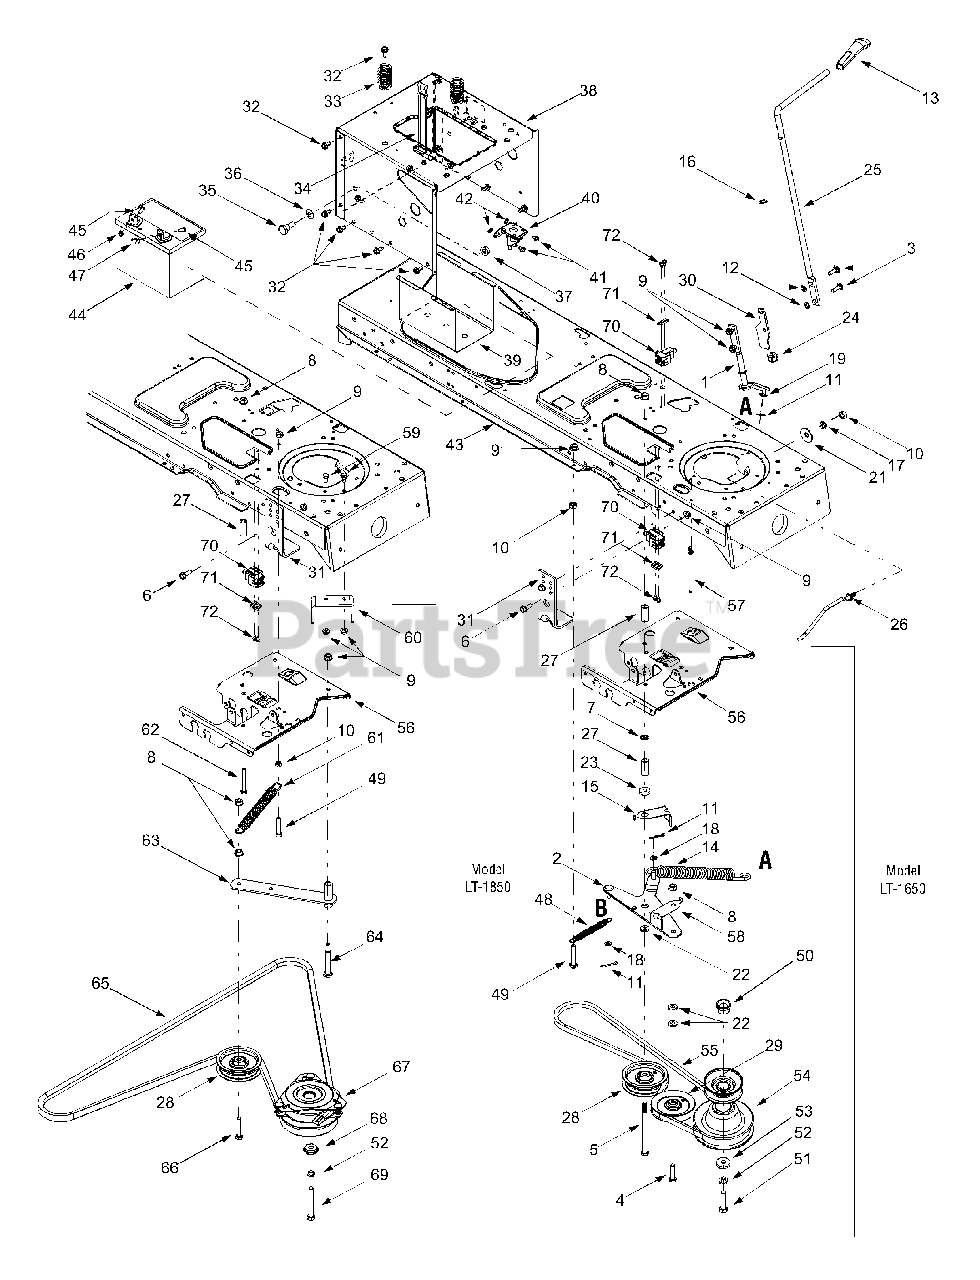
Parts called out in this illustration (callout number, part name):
1	PTO Engage Lever Assembly
4	Hex Cap Screw, 3/8-16 x 1.5
5	Hex Cap Screw, 3/8-16 x 5.5
6	Hex Head Washer Screw, 5/16-18 x .875
7	Push Nut, 3/8
8	Flange Lock Nut, 3/8-16
9	Flange Lock Nut, 5/16-18
10	Hex Nut, 5/16-18
11	Cotter Pin, 1/8 x 1.25
12	Speed Nut, .3125
13	PTO Knob
14	Extension Spring, .75 x 6.75
16	Flat Washer, .510 x .750 x .033
17	Lock Washer, 5/16
18	Flat Washer, .385 x .62 x .063
19	Flat Washer, 5/16
21	Bell Washer, .39 x 1.13 x .062
22	Flat Washer, .407 x .812 x .135
23	Shoulder Spacer, .380
24	Hex Split Flange Bearing, .5
26	Belt Keeper Rod
27	Spacer, 3/8 x 1.54
28	Idler Pulley, 3.5
29	Idler Pulley, 4.0
32	Self Tapping Screw, 5/16-18 x .625
33	Compression Spring, 1.28 x 3.125
34	Battery Strap
35	Shoulder Screw, .625 x .5, 7/16-20
36	Bell Washer, .45 x 1.0 x .062
37	Flange Lock Nut, 7/16-20
41	Self Tapping Screw, 1/4-20 x .5
42	Lock Washer, 1/4
43	Lower Frame Assembly
44	12-volt Battery, 270 CCA
45	Hex Cap Screw, 1/4-20 x .62
46	Hex Sems Nut, 1/4-20
47	Wing Nut, 1/4-20
48	Extension Spring, .50 x 5.0
49	Hex Cap Screw, 5/16-18 x 1.75
50	Spacer Cup
51	Hex Head Cap Screw, 7/16-20 x 1.25
52	Lock Washer, 7/16
53	Flat Washer, .450 x 1.25
54	Engine Pulley, 3.56 OD x 5.56
55	PTO Belt (LT-1650)
57	Keeper Pin, 5/16 x 4.75
58	Belt Guard
59	Hex Cap Screw, 5/16-18 x .625
62	Hex Cap Screw, 3/8-16 x 2.5
65	PTO Belt (LT-1850)
66	Hex Cap Screw, 3/8-16 x 2.0
67	Electric PTO Clutch
68	Shoulder Spacer, 1.38 x .445 x .36
69	Hex Cap Screw, 7/16-20 x 3.25 (Grade 5)
70	Switch
71	Switch Plate
72	Screw, #10-16 x .5
